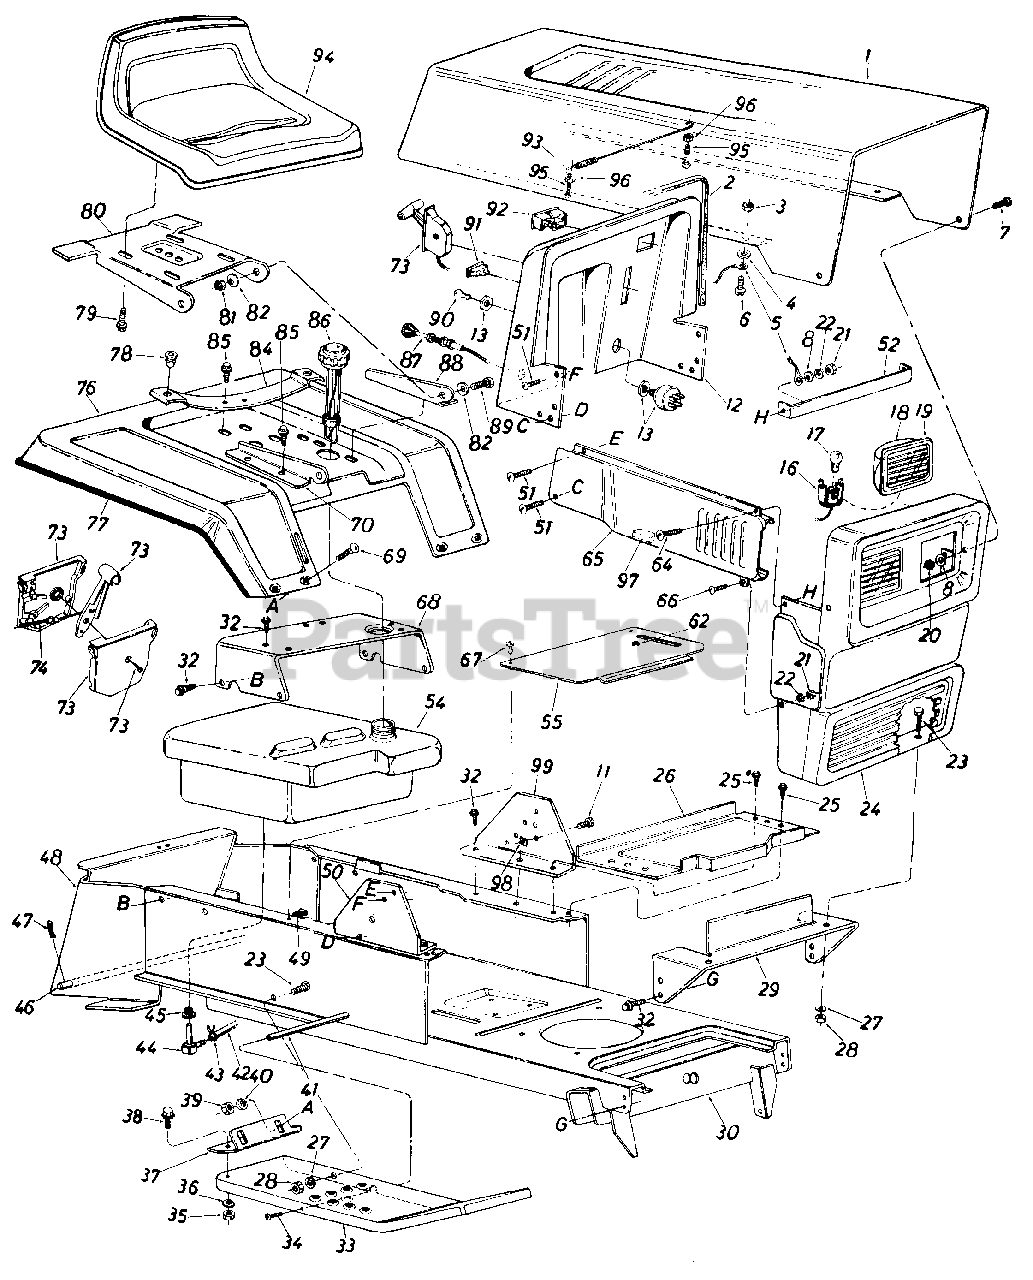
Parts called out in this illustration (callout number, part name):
1	Hood
2	Vinyl Molding Strip-27"
3	Hex Sems Nut #10-24 Thd.
4	Fl-Wash. .20" I.D. x .41" O.D.
5	Hood Stop
6	Truss Hd. Mach. Scr. #10-24 x.50" Lg.
7	Hex Bolt 1/4-20 x .62" Lg.
8	Fl-Wash. 1/4" I.D.*
11	Truss Mach B-Tap Scr. #10 x 1/2" Lg.
12	Dash Ass'y.
13	Ignition Switch
16	Socket
17	Lam p
18	Headlight Housing
19	Lens
20	Hex L-Nut 1/4-20 Thd.
21	Hex Nut 1/4-20 Thd.
22	L-Wash. 1/4" I.D.
23	Hex Bolt 5/16-18 x .75" Lg.
24	Grille
25	Hex Wash. Hd. AB-Tap Scr. 1/4 x.50" Lg.
26	Battery Plate
27	L-Wash. 5/16" I.D.
28	Hex Nut 5/16-18 Thd.
29	Grille Mounting Bracket
30	Lower Frame Ass'y.
32	Hex Thd. Rolling Scr. 5/16-24 x .75" Lg.
33	Running Board-R.H.
34	Truss Mach. Scr. 5/16-18 x .75" Lg.
35	Hex Nut 5/16-18 Thd.
36	Bell-Wash..34" I.D.
39	Hex Nut 1/4-20 Thd.
40	L-Wash. 1/4" I.D.
41	Running Board Rod
42	Fuel Line 44" Lg.
43	Hose Clamp 3/8"
44	90ø Elbow
45	Bushing
46	Hitch Rod
47	Internal Cotter Pin
48	Hitch Plate
49	Speed Nut
50	Dash Support Brkt.-R.H.
51	Hex Wash Hd. Tap Scr. 1/4 x .75" Lg.
52	Tie Strap-Grille Side Panel
54	Fuel Tank
55	Transmission Cover Ass'y.
62	Snap Bushing
64	Truss Hd. Scr. 1/4-20 x .75" Lg.*
65	Side Panel-R.H.
66	Truss Mach. Scr. 1/4-20 x .50" Lg.*
67	Truss Mach. B-Tap Scr. #10 x.50" Lg.
68	Seat Mounting Channel
69	Carriage Bolt 1/4-20 x .50" Lg.*
70	Seat Bracket-R.H.
73	Throttle Control Box Ass'y.
74	Throttle Control Wire
78	Grommet
79	Hex Wash. Hd. AB-Tap Scr. 3/8 x .75" Lg.
80	Seat Pivot Bracket
81	Hex Cent. L-Nut 5/16-18 Thd.
82	Belleville Wash. .34" I.D. x .88" O.D.
84	Seat Spring
85	Hex Wash. Hd. Self-Tap Scr. 5/16-18 x .50" Lg.
86	Gas Cap w/Gauge
87	Choke Control Comp.
88	Seat Bracket-L.H.
89	Hex Bolt 5/16-18 x .75" Lg.*
90	Ignition Key
91	Light Switch
92	Ammeter
93	Hood Spring
94	Seat Ass'y.
95	Hex Bolt #10-24 x 1.0" Lg.
96	Hex Sems Nut #10-24
97	Rubber Strip 1/2" Sq. x 2-1/2" Lg.
98	Speed Nut #10-24
99	Dash Support Brkt.-L.H.
